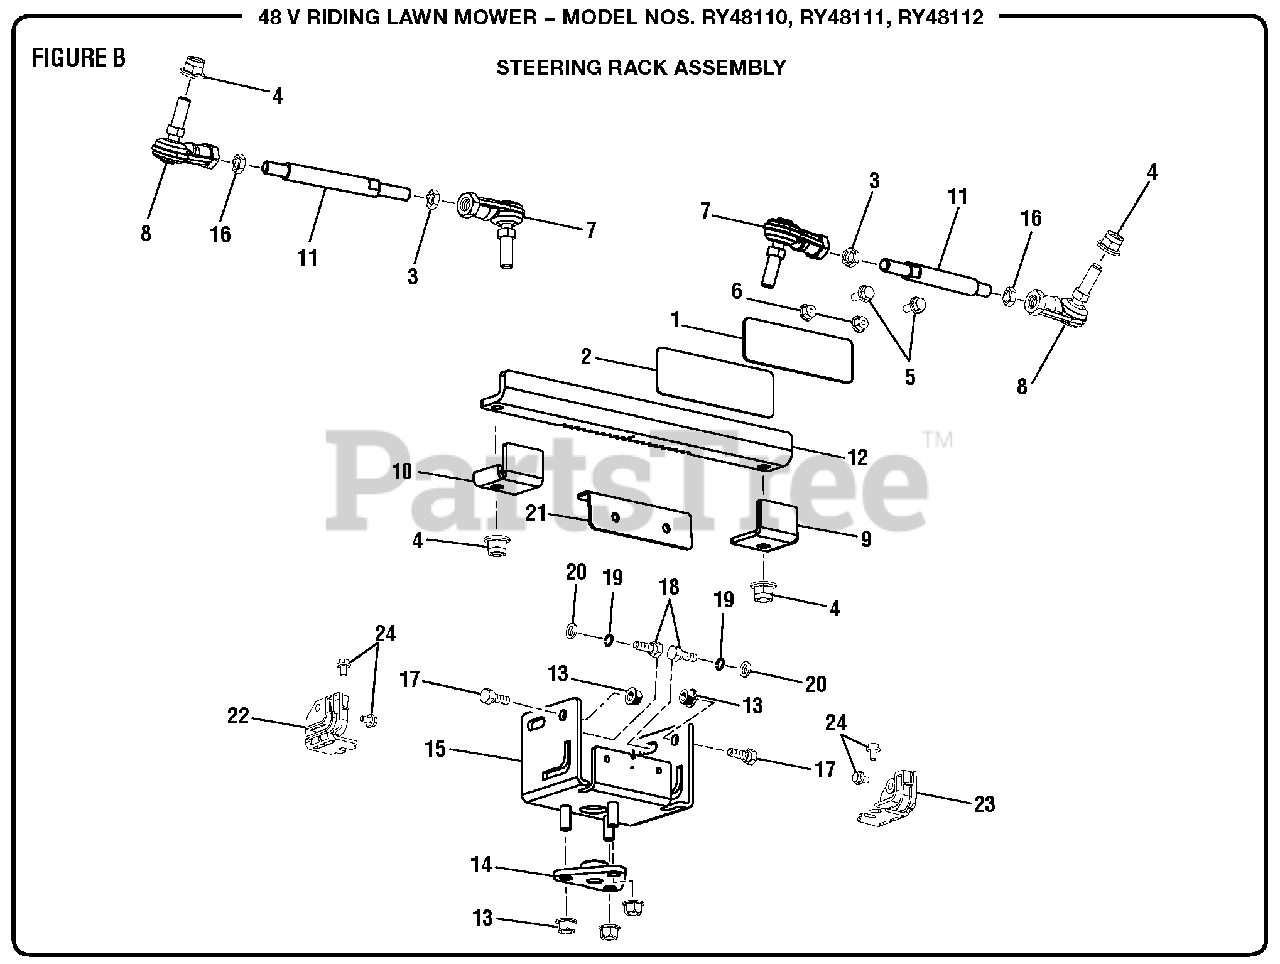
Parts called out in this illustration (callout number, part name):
1	Steel Pad
2	Shim Steering Rack
3	Nut (M10)
4	Flange Lock Nut (M10 x 1.25 mm)
5	Flange Bolt (M6 x 14 mm, Hex Hd.)
6	Flange Nut (M6)
8	Rod End 2
9	Left Rack Limiter
10	Right Rack Limiter
12	Steering Rack
13	Flange Nut (M8)
14	Steering Shaft Seat
15	Seat Bracket
16	Hex Nut (M10 x 1.25 mm, Left Hand)
17	Hex Bolt (M8 x 25 mm)
18	Bolt (M8 x 25 mm, Hex Hd.)
19	Lock Washer (M8)
20	Washer (M8)
21	Rack Shim Limiter
22	Rack Bushing (Right)
23	Rack Bushing (Left)
24	Bolt (M5 x 8 mm, Hex Flange Hd.)
